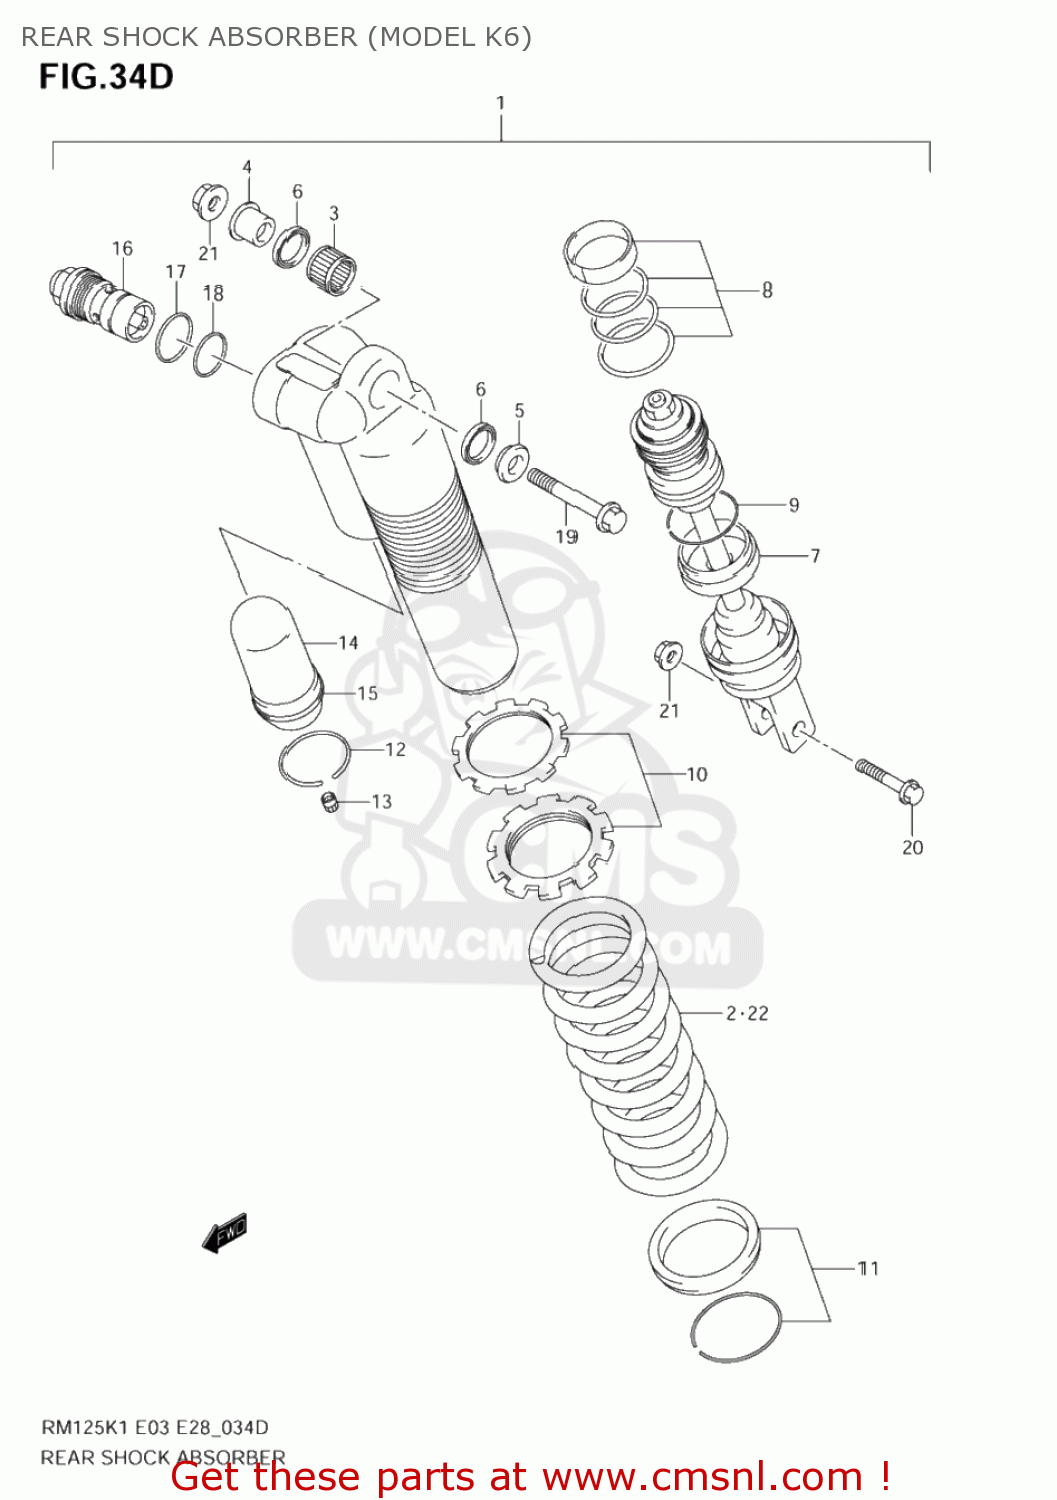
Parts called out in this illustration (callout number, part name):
1	ABSORBER ASSY,RR SHOCK
2	SPRING,RR(SOFT K=5.1)
3	BEARING(16X22X12)
4	SPACER,UPPER BRG,R
5	SPACER,UPPER BRG,L
6	SEAL,OIL(16X22X2.5)
7	ROD,PISTON
8	O RING SET
9	RING,STOPPER
10	ADJUSTER SET
11	SPRING SEAT SET
12	RING,STOPPER
13	CAP
14	BLADDER
15	CAP,CHAMBER
16	BOLT,PLUG
17	O RING
18	O RING,CTR BOLT UPR
19	BOLT(10X65)
20	BOLT,RR SHOCK ABSORBER LWR
21	NUT
22	SPRING,RR(K=4.6)
